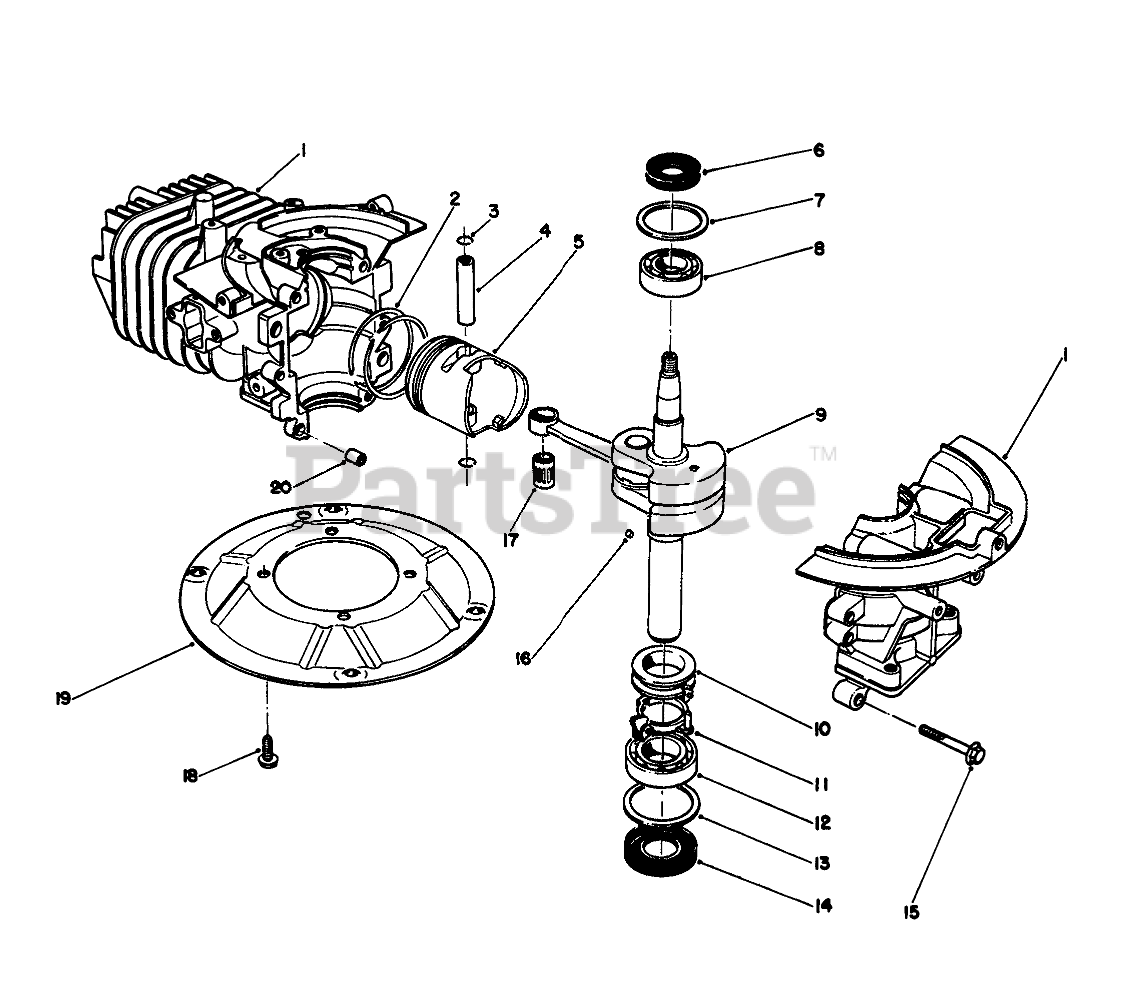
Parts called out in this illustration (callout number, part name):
1	CRANKCASE
2	RING SET
4	PIN-PISTON
5	PISTON
6	OIL SEAL
7	WASHER-UPPER
8	BEARING-UPPER
9	CRANKSHAFT
10	SPACER
11	BRACKET
12	LOWER BRG
13	WASHER-LOWER
14	SEAL-OIL
17	BEARING
19	PLATE-MOUNTING
